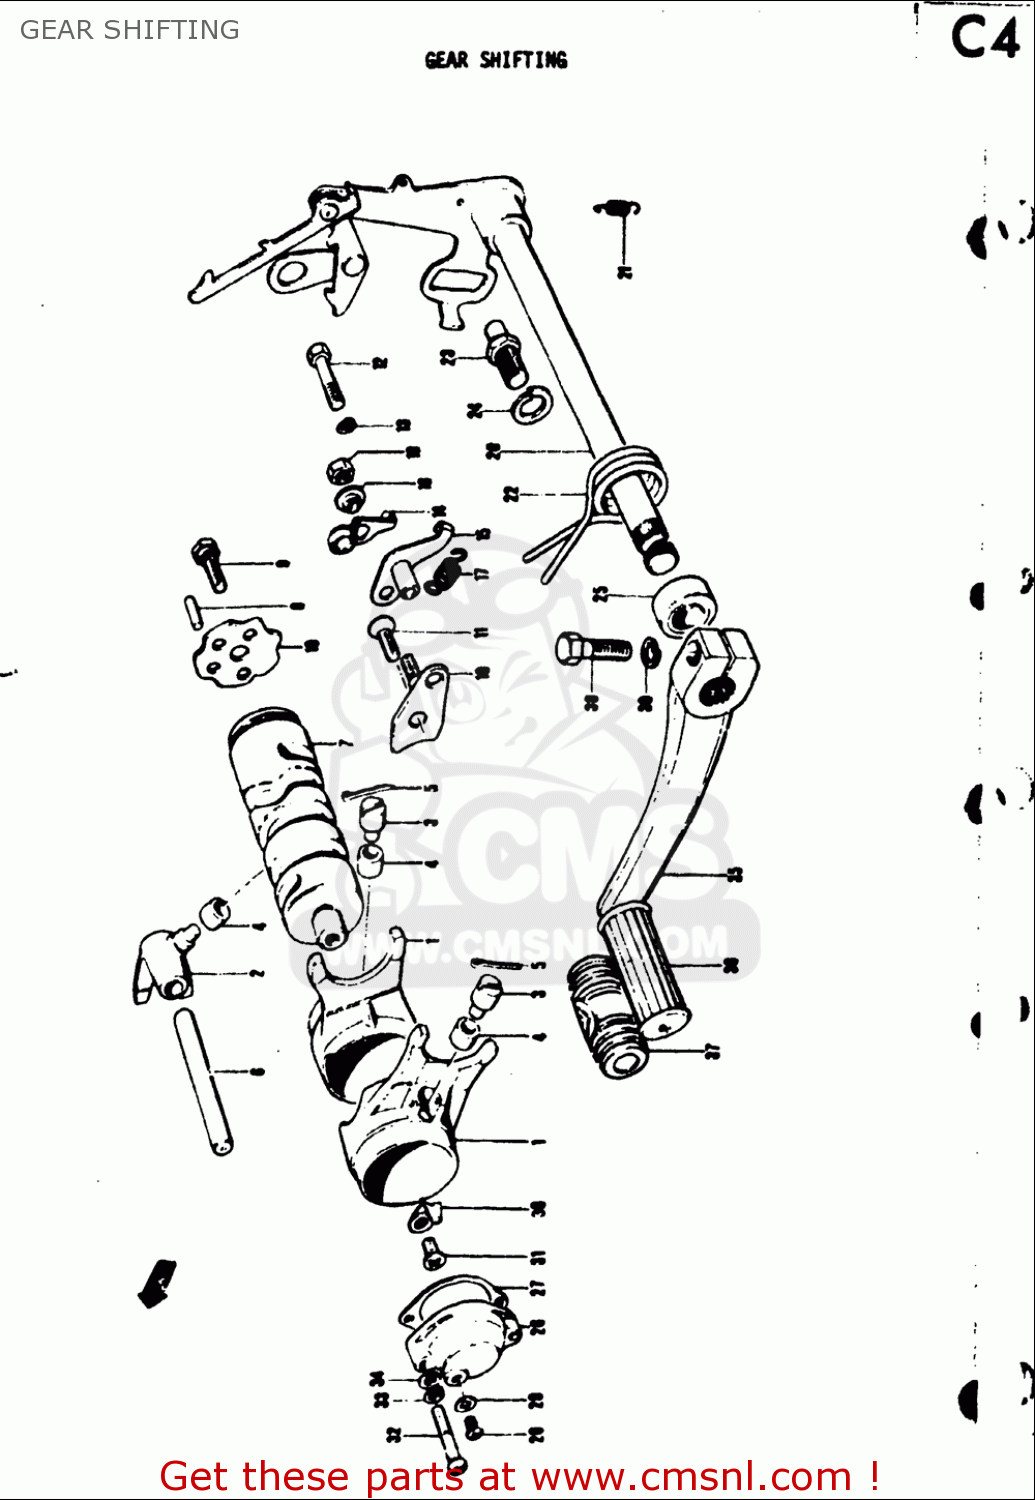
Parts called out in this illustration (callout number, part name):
1	FORK,GEAR SHIFT NO.1
3	PIN
4	SPACER(6X9.8X6)
5	PIN
6	SHAFT,GEAR SHIFT FORK
8	ROLLER(4X13.8)
9	BOLT
11	SCREW
12	BOLT
13	WASHER,LOCK
18	NUT
21	SPRING
22	SPRING
24	WASHER,LOCK
25	SEAL,OIL (12X22X9)
26	BODY,GEAR SHIFT SWITCH
27	28
28	SCREW
29	WASHER
30	CONTACT,GEAR SHIFT SWITCH
31	SCREW
32	SCREW
33	WASHER,LOCK
34	WASHER
35	LEVER ASSY,GEAR SHIFT
36	RUBBER,GEAR SHIFT PEDAL
37	RUBBER,GEAR SHIFT PEDAL
38	BOLT
39	WASHER,LOCK
